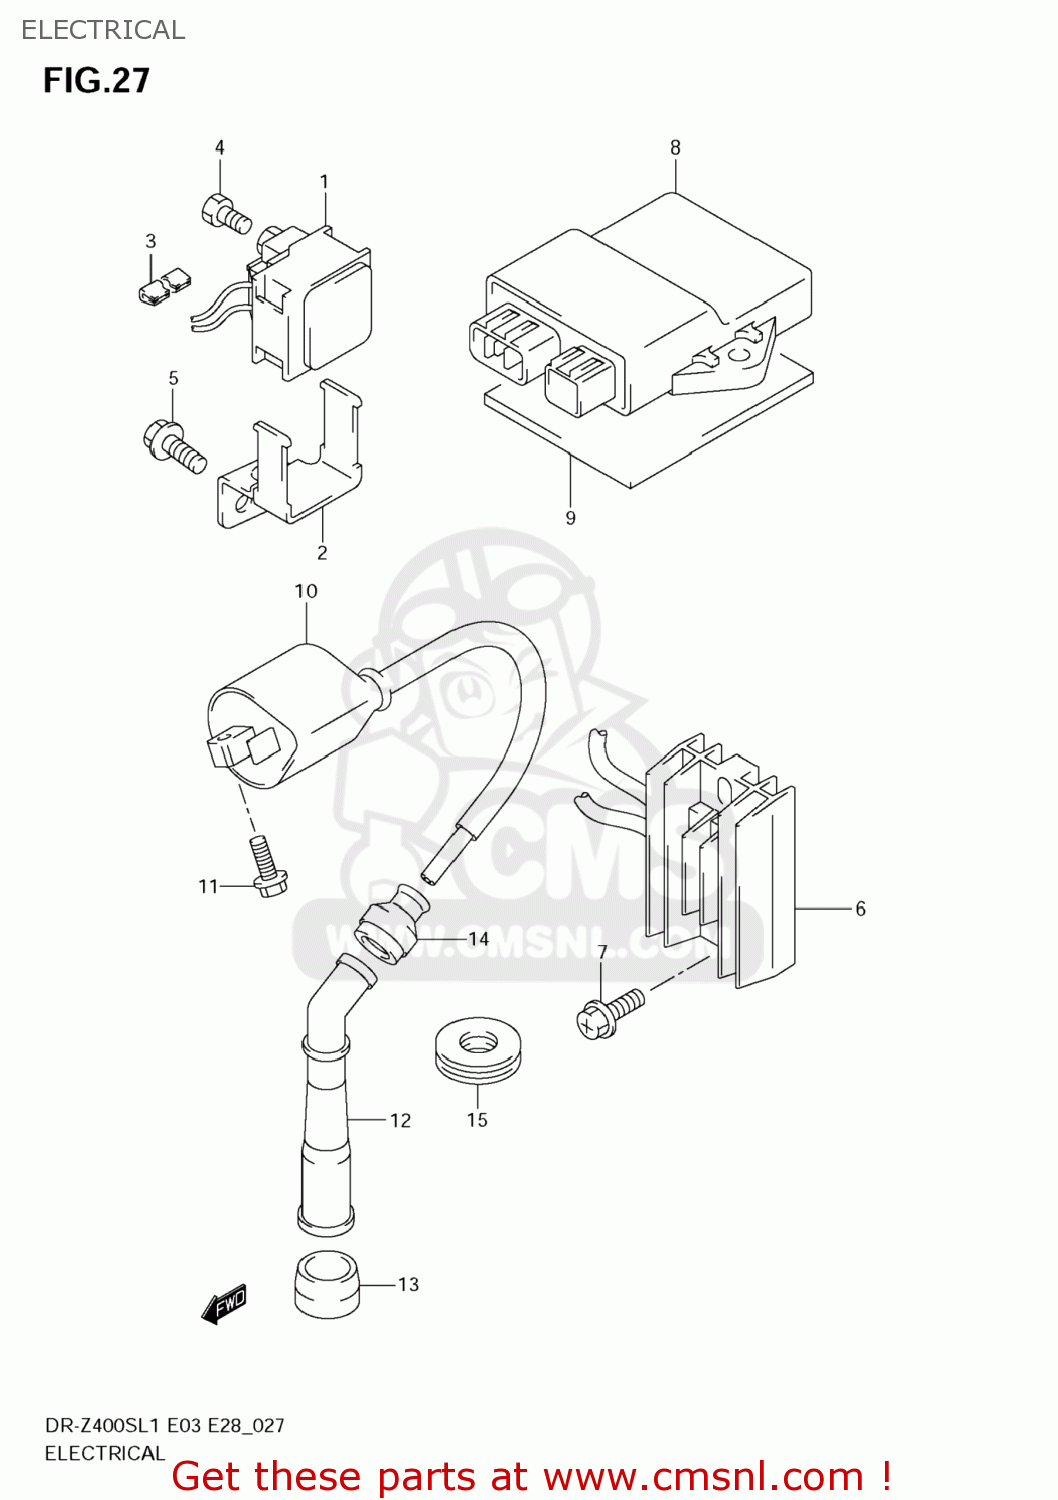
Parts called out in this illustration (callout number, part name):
1	RELAY ASSY,STARTING MOTOR
2	BRACKET,STARTING MOTOR RELAY
3	PROTECTOR,STARTING MOTOR LEAD
4	SCREW(6X8)
5	BOLT
6	RECTIFIER ASSY
7	SCREW
8	CDI UNIT
9	CUSHION(30X50X3)
10	COIL ASSY,IGNITION
11	BOLT
12	CAP,SPARK PLUG
13	SEAL,SPARK PLUG
14	SEAL,HIGH TENSION CORD
15	COVER,SPARK PLUG CAP
